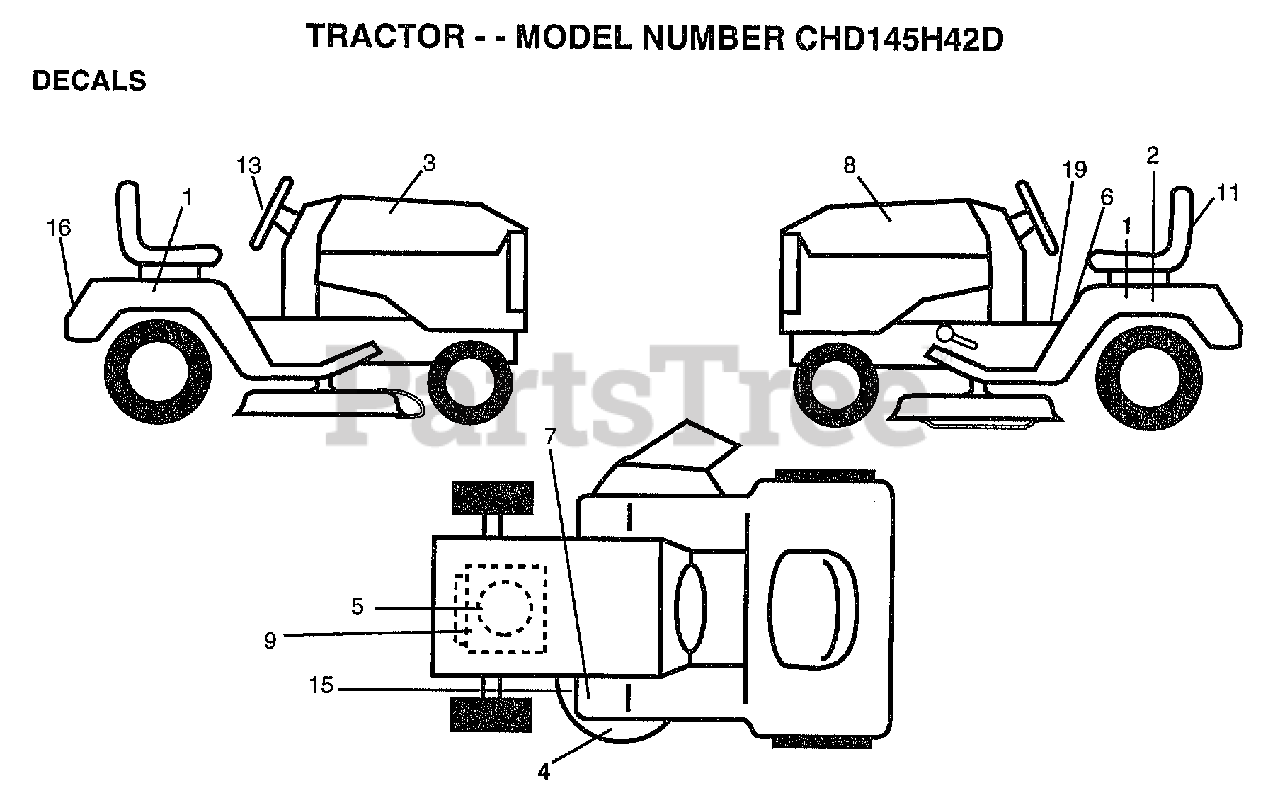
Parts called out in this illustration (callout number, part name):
1	"DECAL FENDER,SD"
2	DECAL.BATRY.3-3908
3	"DECAL-HOOD,RH"
4	"DECAL DECK,MULCH"
5	DECAL.ENGINE
6	DECAL.CAUT.ENG/FR
7	DECAL T
8	"DECAL-HOOD,LH"
9	DECAL.ENGINE.STET
11	"DECAL SEAT,ACC"
13	"DECAL WHEEL,STEER"
15	"DECAL-SCHEM,BELT"
16	"DECAL FENDER,LOGO"
19	DECAL SADDLE OPER
